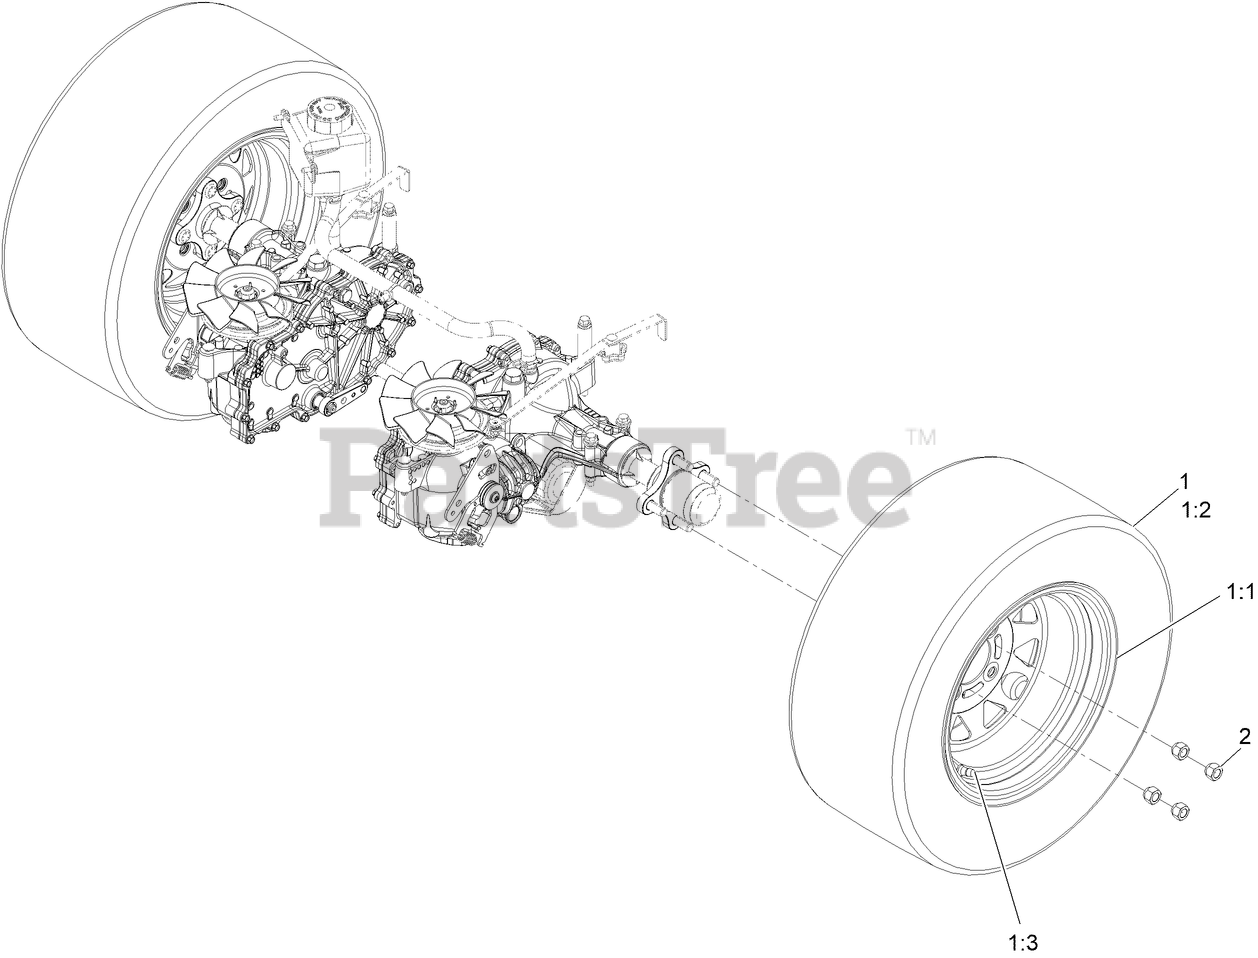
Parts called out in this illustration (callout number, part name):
1	WHEEL AND TIRE ASM
1:3	VALVE
2	NUT-LUG
